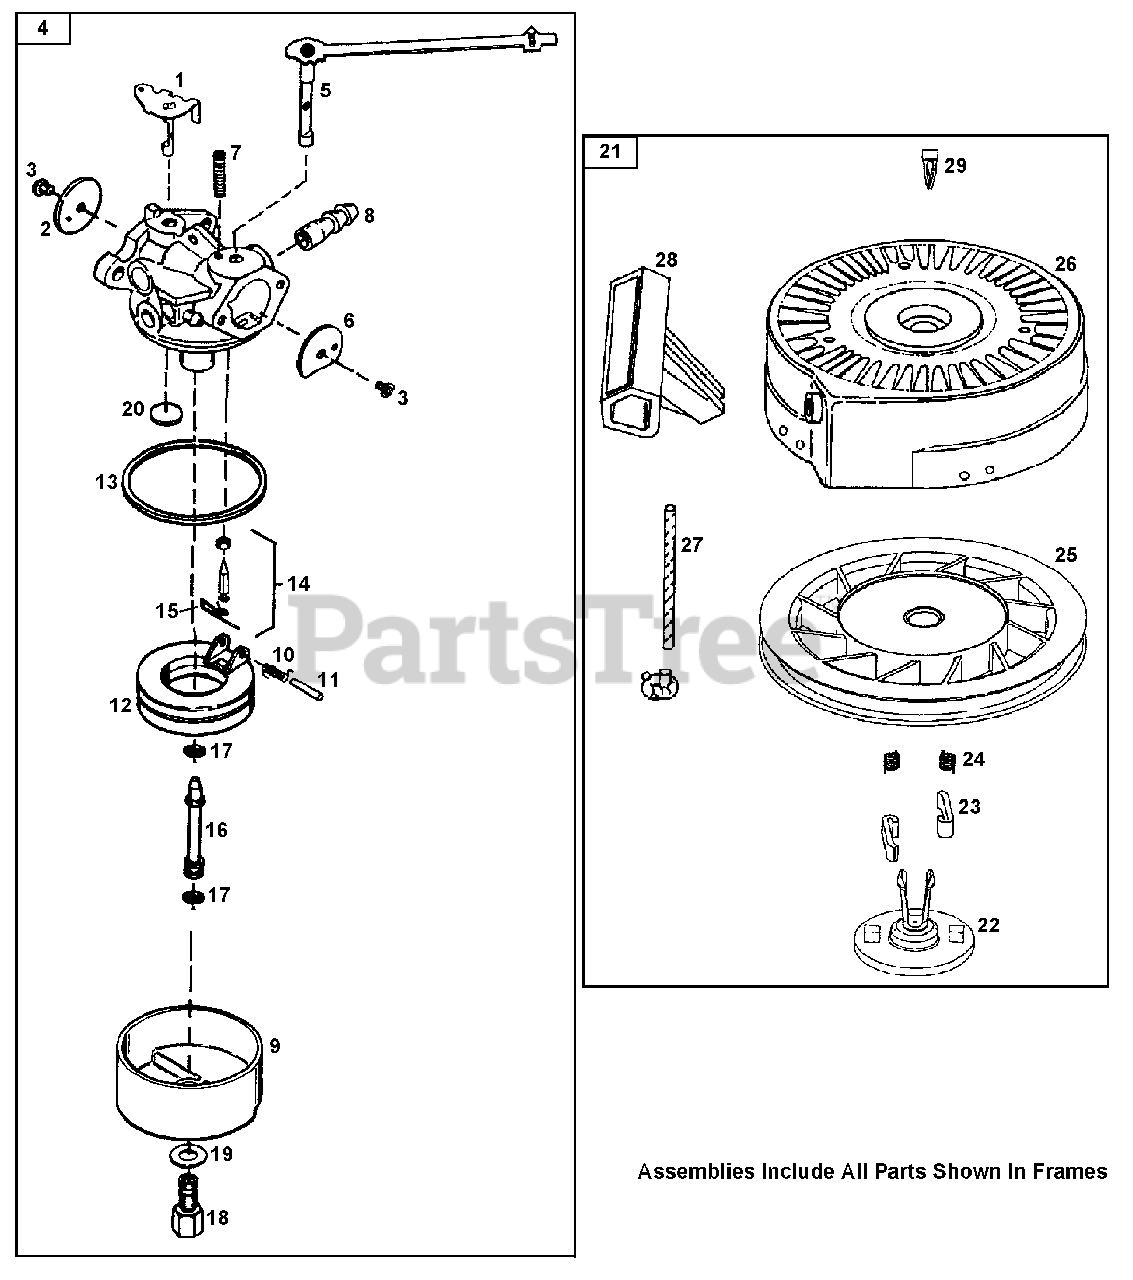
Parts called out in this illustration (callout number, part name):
1	Throttle Shaft & Lever Ass’y
2	Throttle Shutter
3	Shutter Screw
4	Carburetor Assembly
5	Choke Shaft & Lever Ass’y
6	Choke Shutter
7	Choke Positioning Spring
8	Fuel Fitting
9	Float Bowl
10	Float Dampening Screw
11	Float Shaft
12	Float
13	Float Bowl O-Ring
14	Inlet Needle, Seat & Clip
15	Spring Clip
16	Main Nozzle Tube
17	O-Ring Main Nozzle Tube
18	High Speed Bowl Nut
19	Bowl Nut Washer
20	Welch Plug, Atmospheric Vent
21	Rewind Starter Ass’y
23	Starter Dog
24	Dog Spring
25	Pulley Ass’y
26	Starter Housing Ass’y
27	Starter Rope (98")
28	Starter Handle
29	Locking Tab
